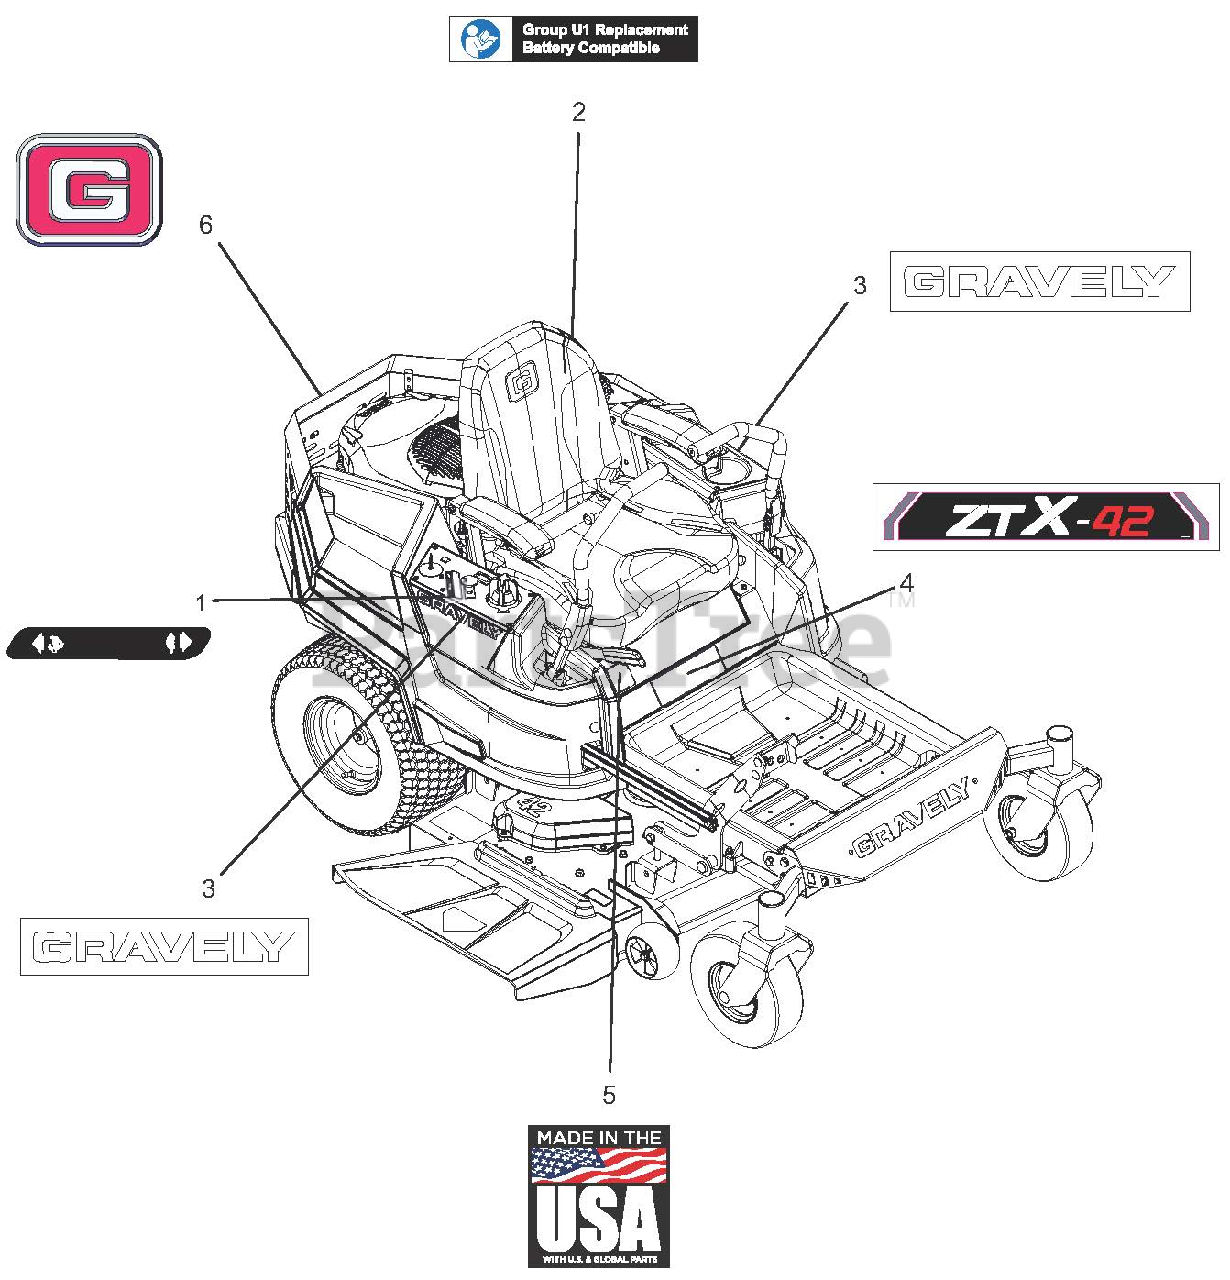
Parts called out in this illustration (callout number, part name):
1	DECAL, DASH DECAL
2	DECAL, U1 BATTERY REPLACEMENT
3	DECAL, 9.5" GRAVELY LOGO
4	DECAL, GRAVELY ZT X 42
5	DECAL, MADE IN USA
6	DECAL, GRAVELY BRAND
